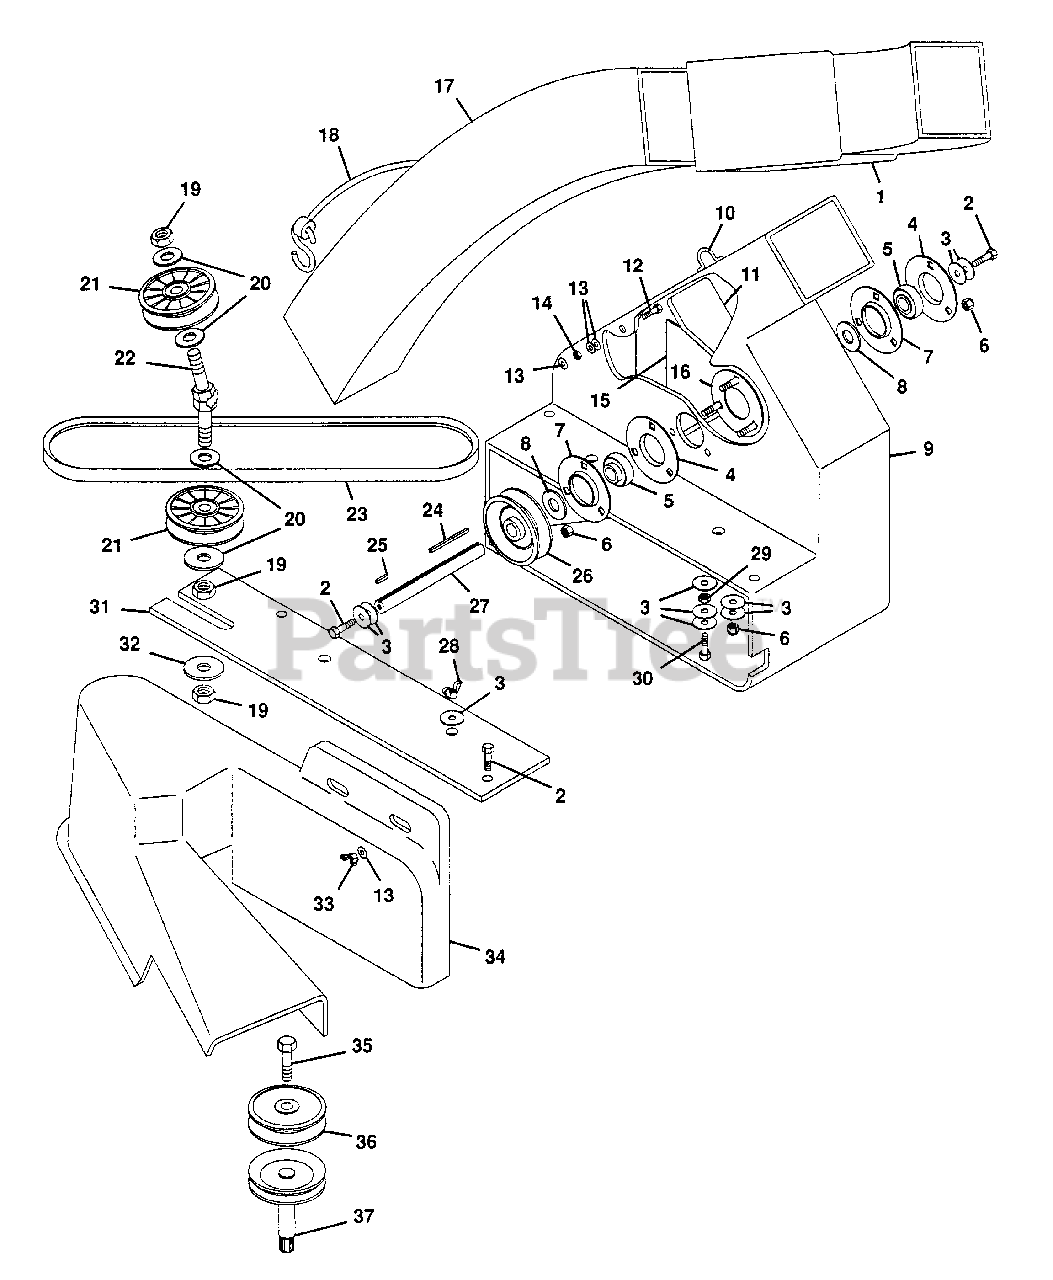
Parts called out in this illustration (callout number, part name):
1	Chute, Short Curved
2	Bolt, Hex 5/16-18x.75
3	Washer, Flat .312x.734x.065
4	Flangettte, Inner Wall
5	Bearing, 3/4 Shaft
6	Nut, Lock 5/16-18
7	Flangette, Outer
8	Bush., #10
9	Shell, Blower
10	Hook, Chute
11	Fan(Impeller)
12	Bolt, Hex 1/4-20x1.00
13	Washer, Flat .265x1.250x.063
14	Nut, Hex 1/4-20
15	Plate, Wall Support w/Flangette
16	Flangette, Retaining Wall Inner
17	Tube, Grass Catcher
18	Assembly, Cord
19	Nut, Hex 5/8-11
20	Spacer, 5/8
21	Idler, 4" with 5/8 Bore
22	Shaft, Double Idler
23	Belt, AX-66
24	Key, Square .188x2.50
25	Key, Square .188x.50
26	Sheave, Fan(4" Driven)
27	Shaft, 3/4 Fan
28	Nut, Wing 5/16-18
29	Nut, Lock 5/16-18
30	Bolt, Hex 5/16-18x1.25
31	Plate, Blower Mounting
32	Washer, Flat .656x1.250x.100
33	Nut, Wing 1/4-20
34	Guard, Belt(Large)
35	Bolt, Hex 1/2-13x2.00 L.H. Thd.
36	Pulley, Drive
37	Weldment, Spindle Shaft
NS	Decal, Danger(HANDS)
NS	Decal, Danger(SHIELD)
NS	Decal, Danger
